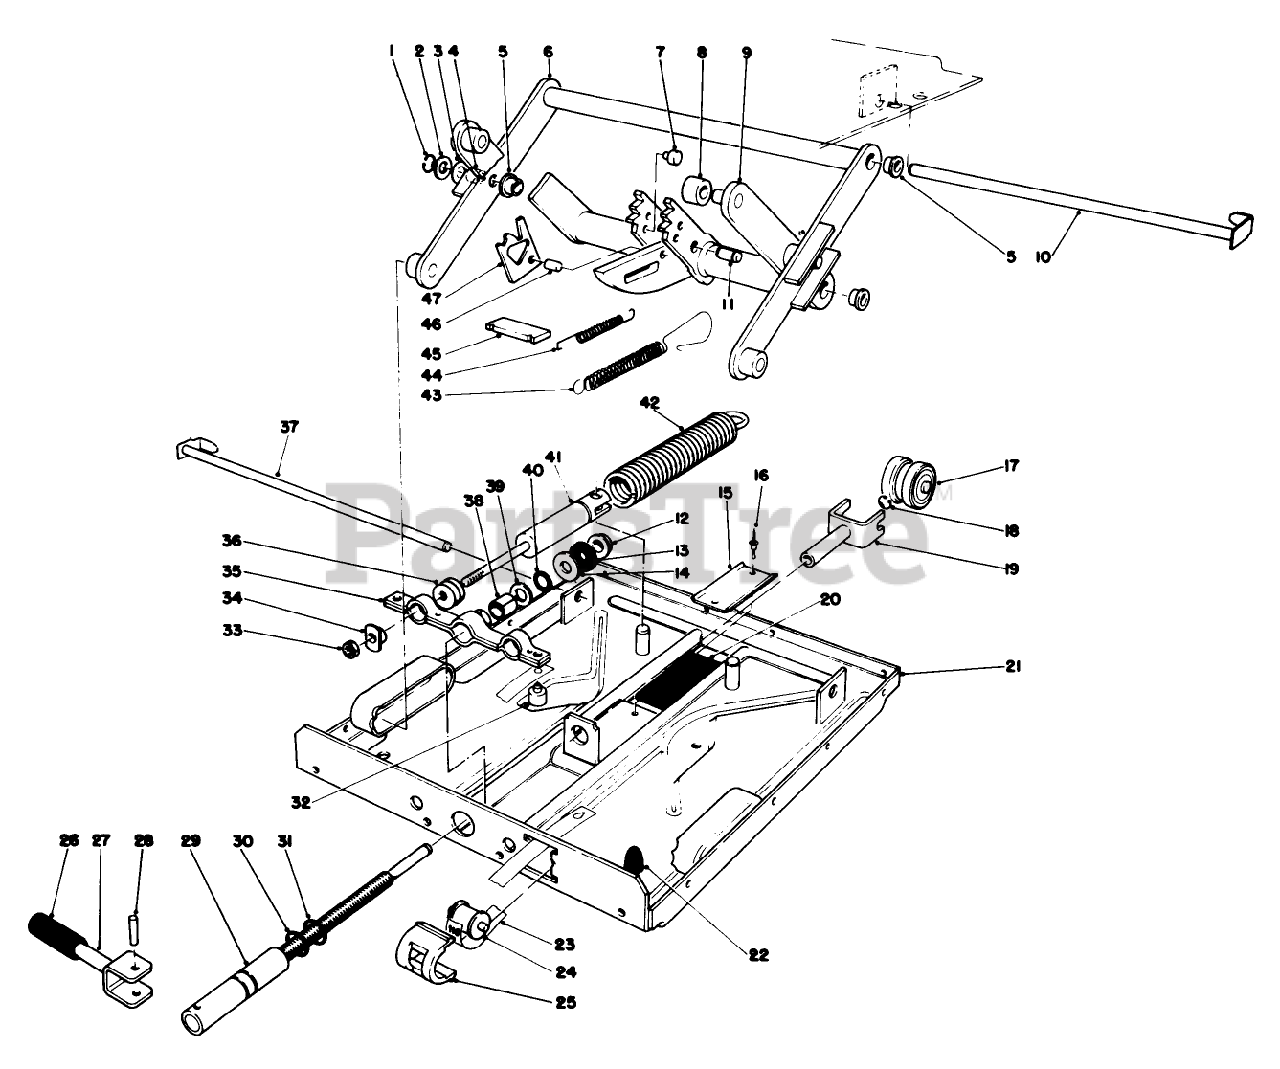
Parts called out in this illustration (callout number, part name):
1	WASHER
2	WASHER
3	WASHER
4	BRG BSHG
5	BEARING
6	Swing Arm-Outside
8	ROLLER
9	Frame Bag
11	Grooved Locking Pin 08X16CM
12	SLEEVE
13	WASHER-RUBBER
14	WASHER
15	U-TRACK
16	RIVET
17	TRIBLE BRG
18	RET RING
20	RUBBER
21	Lower Suspension Plate-Complete (Incl.Ref.#15-16 & 20)
22	BUMPER
23	WEIGHT INDICATOR BAND
24	ROLLER
25	GUIDE-SLEEVE
26	HANDLE
27	TOGGLE
28	GROOVED PIN
30	RUBBER RING 14MM BLK
31	RUBBER RING 14MM RED
34	WELD NUT
35	Spring Bracket
36	THREADED ROD
38	SLEEVE
39	WASHER
40	BEARING-THRUST, NEEDLE
41	SHOCK ABSORBER
42	COIL SPRING
43	SPRING-COIL
44	SPRING-COIL
45	PLATE
47	BRACKET-RELEASE
